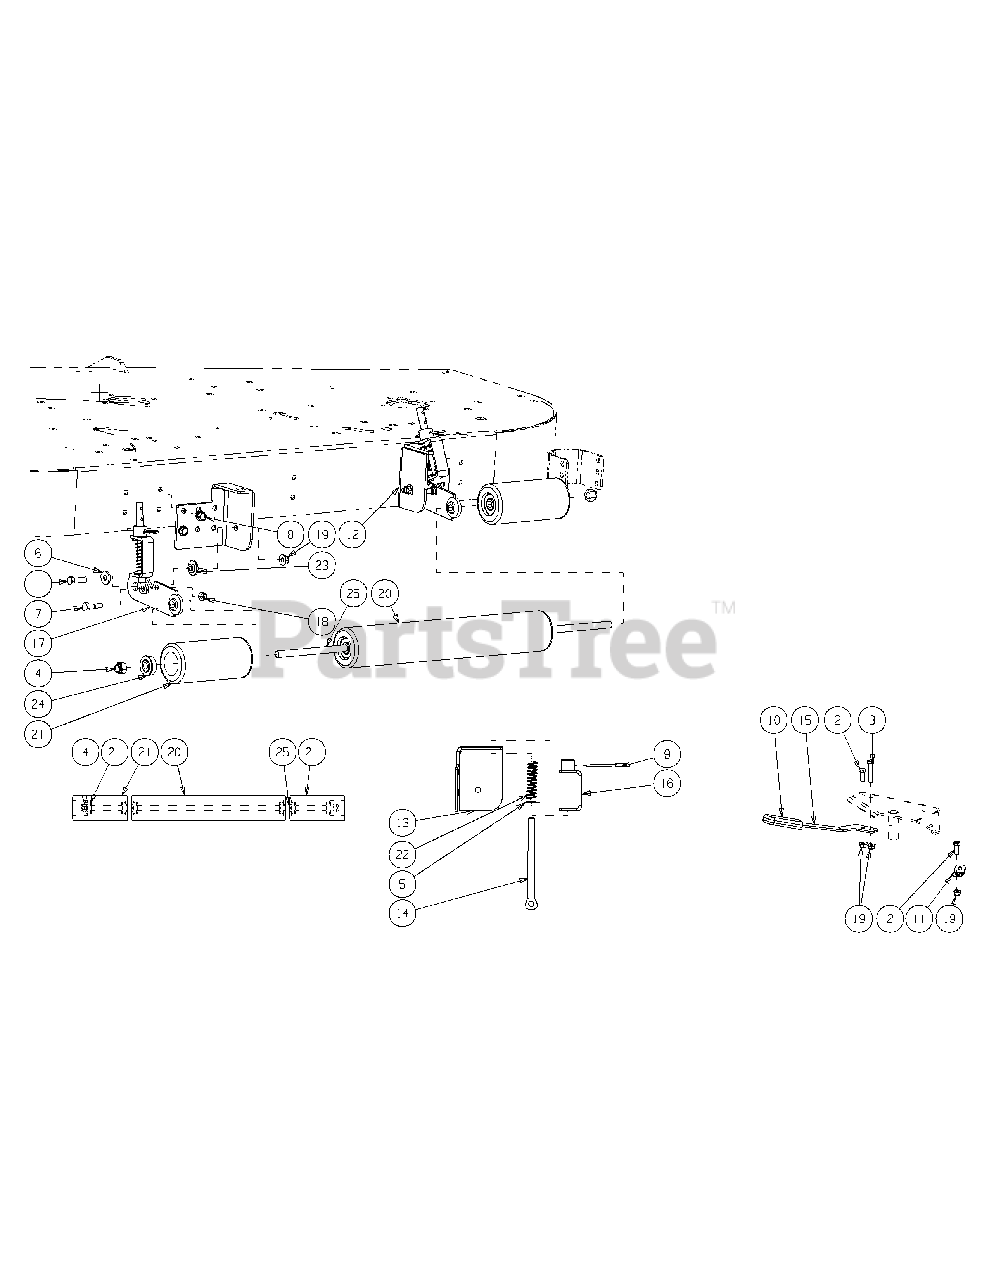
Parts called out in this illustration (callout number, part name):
1	HHCS, 3/8-16 x 1-1/4
2	HHCS, 3/8-16 x 1.00
3	HHCS, 3/8-16 x 2.00
4	Nut, 1/2-13, Nylon Insert
5	Washer, 1/2 Zinc
6	Flat Washer, .406 ID, 1.0 OD, .105
7	Shoulder Bolt
8	Hex Index Washer Screw, 3/8-16,.5
9	HitchPin, .120 Dia. x 3.0
11	Spring Mounting Bracket, 45 degree
17	Striper Arm Bracket Assembly
18	Nylon Nut, 5/16-18, Flangelock
19	Nylon Nut, 3/8-16, Flangelock
20	Roller, 18.20" w/ Insert
21	Roller, 6.5" w/ Insert
22	Compression Spring, .72 OD x 2.75
23	Shoulder Spacer, .625 Dia. x .190
24	Roller Bearing, .5" ID
25	Striper Roller Rod
